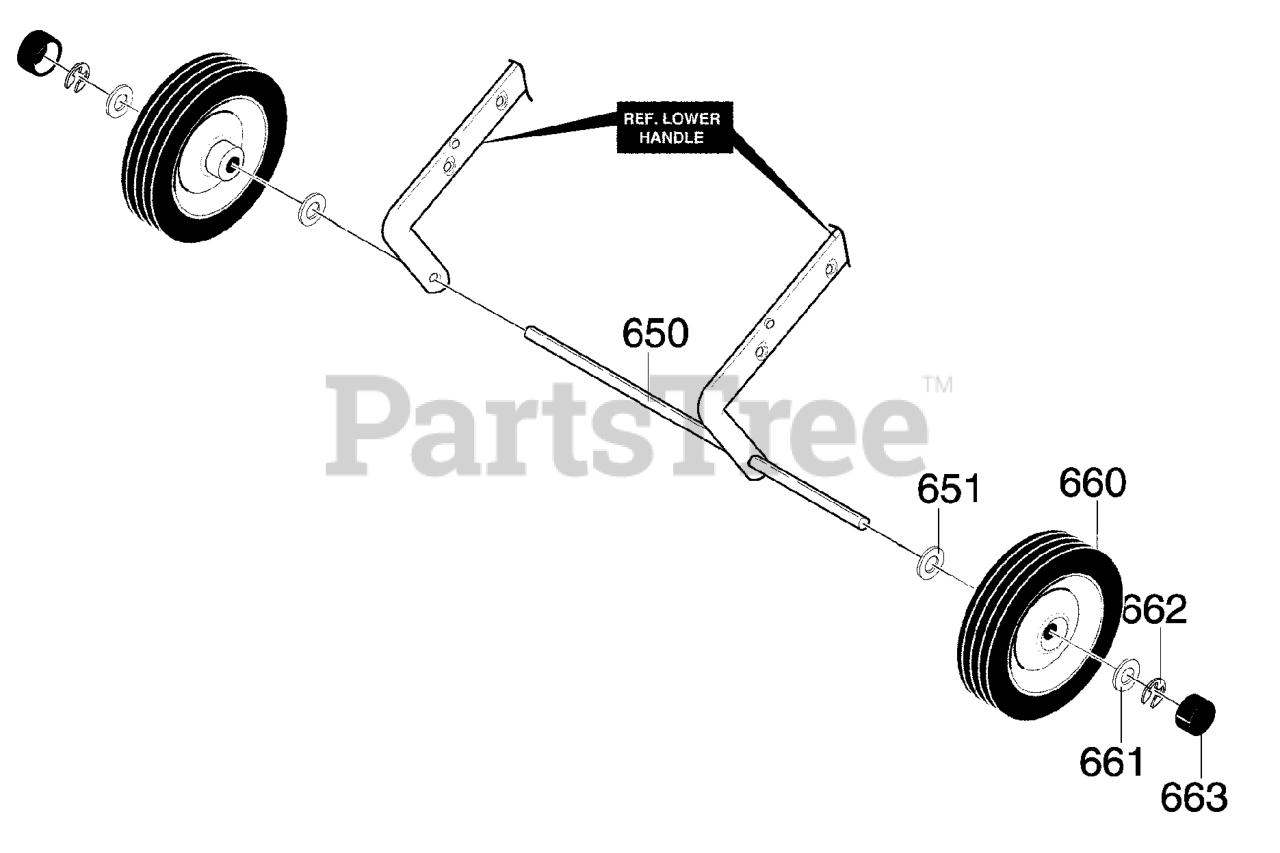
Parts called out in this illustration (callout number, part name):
650	AXLE, 7 x 1.5
651	FLATWASHER
660	TIRE & RIM
661	FLATWASHER
663	HUB CAP
